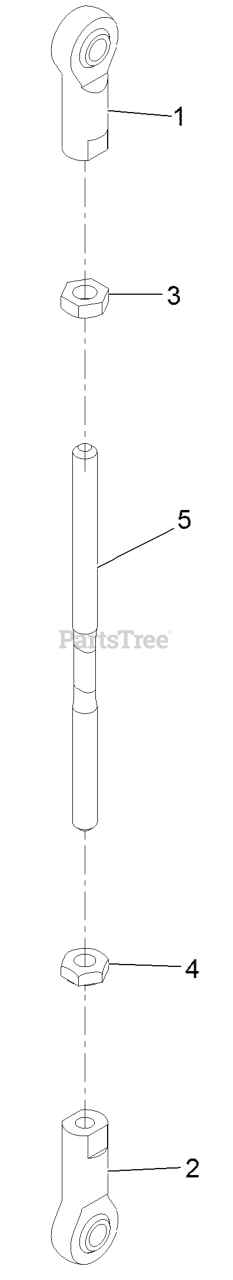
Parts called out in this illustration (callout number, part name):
1	ROD END-BALL JOINT
2	JOINT-BALL, LH
3	NUT-JAM
4	NUT-JAM
